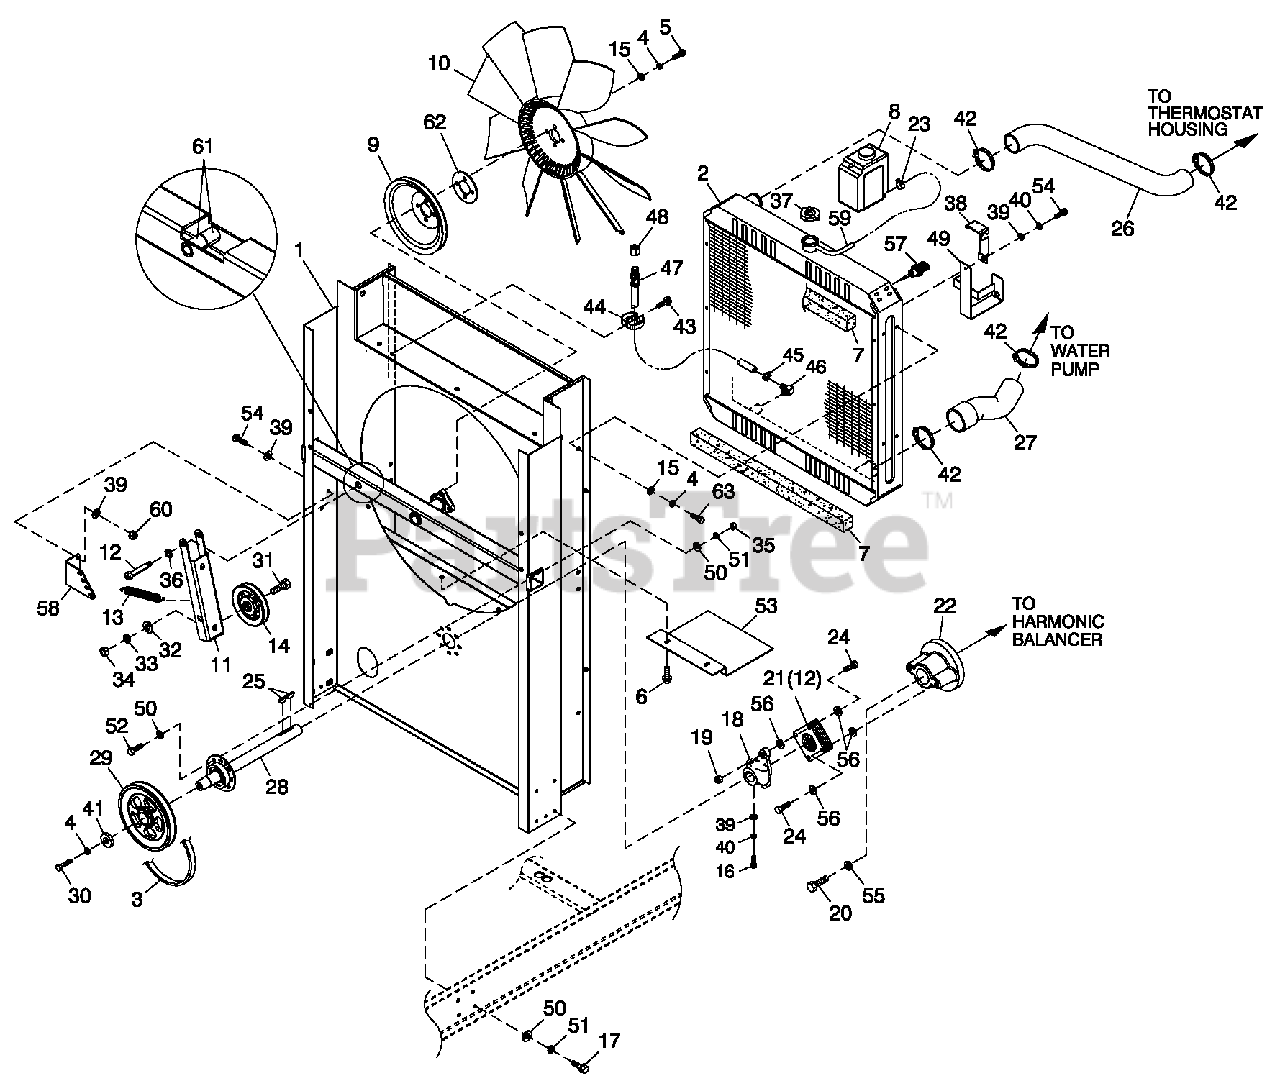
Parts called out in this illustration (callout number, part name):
1	WELDMENT RADIATOR SUPPORT C5
2	RADIATOR 680 X 680 X 70 CPL
3	V-BELT 31/64" X 62-3/8"
4	WASHER LOCK M10
5	SCREW HHC M10-1.5 X 30 C10.9
6	SCREW THF M6-1 X 16 N WA Z/JS
7	TAPE FOAM 1 X 1 (26.75" LG)
8	TANK COOLANT RECOVERY
9	PULLEY FAN V-GROOVE 9"
10	FAN 26" LH ROTATION
11	ARM BELT TENSIONER
12	SHOULDER BOLT 1/2 X 2-1/4"
13	SPRING TENSION CPL
14	PULLEY V-BELT 4" FLANGED
15	WASHER FLAT 3/8-M10 ZINC
16	SCREW HHC M8-1.25 X 45 C8.8
17	SCREW HHFC M6-1.0 X 20 G8.8
18	HUB FLEX PLATE
19	NUT HEX LOCK 5/16-24 NY INS
20	SCREW HHC M12-1.5 X 60 G8.8
21	DISK FLEX
22	COUPLING FLEX HUB MACHINED
23	CLAMP HOSE BAND 1/4
24	SCREW HHC 5/16-24 X 1.124
25	KEY WOODRUFF 4 X 19D
26	HOSE RADIATOR UPPER CPL
27	HOSE LOWER RAD G3 4.6L (FWD)
28	ASSY BRG/SHAFT CPL FANDRIVE
29	PULLEY 5.5" DIA MACHINED
30	SCREW HHC M10-1.5 X 30 G8.8
31	SCREW HHC 1/2-13 X 2" G8
32	WASHER FLAT 1/2 ZINC
33	WASHER LOCK 1/2
34	NUT HEX 1/2-13 STEEL
35	NUT HEX M6 X 1.0 G8 YEL CHR
36	WASHER NYLON .50 X .87 X .06
37	CAP RADIATOR 13 PSI
38	BRACKET, SIGNAL CONDITIONER
39	WASHER FLAT 5/16-M8 ZINC
40	WASHER LOCK M8-5/16
41	SPACER .5 X 1.5 X .25 STL/ZINC
42	CLAMP HOSE #28 1.32-2.25
43	SCREW HHTT M4-0.7 X 8 BP
44	SPRING CLIP HOLDER .37-.62
45	CLAMP HOSE .38-.87
46	BARBED EL 90 3/8 NPT X 3/8
47	HOSE DRAIN ASSY 28"
48	CAP HEX 1/4 NPT BRASS
49	BRACKET COOLANT TANK
50	WASHER FLAT 1/4-M6 ZINC
51	WASHER LOCK M6-1/4
52	SCREW HHC M6-1.0 X 20 G8.8
53	SHIELD RADIATOR
54	SCREW HHC M8-1.25 X 20 G8.8
55	WASHER LOCK M12
56	WASHER FLEX (THIN)
57	PROBE COOLANT LEVEL 3/8-18NPTF
58	BRACKET TENSIONER SPRING
59	HOSE 9/32 ID (43"LG)
60	NUT HEX LOCK M8-1.25 NY INS
61	BEARING SLEEVE 1/2/ X 3/4 X 1
62	SPACER CPL COOLING FAN 1/8"
63	SCREW HHC M10-1.5 X 20 C8.8
